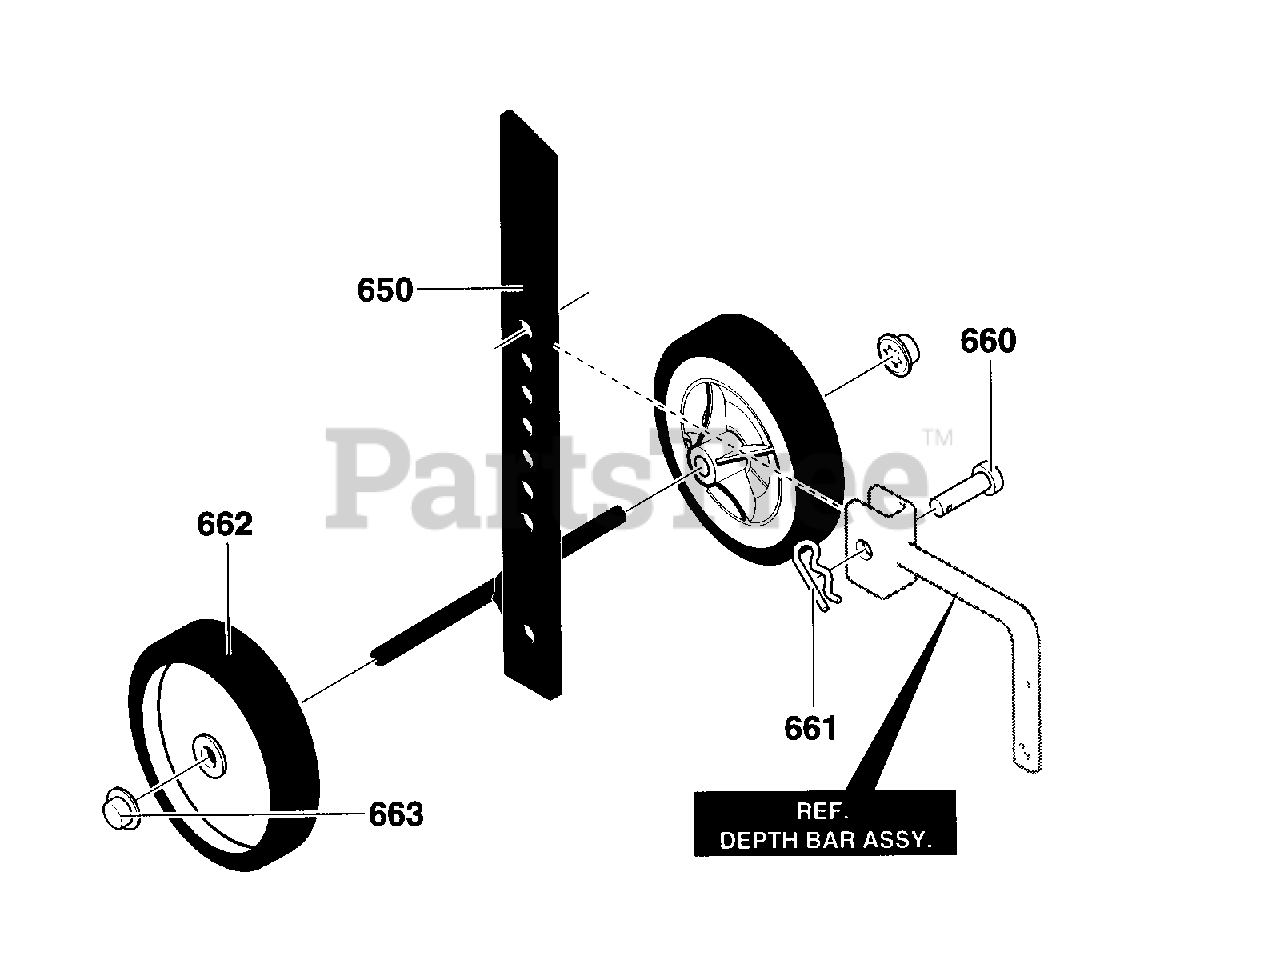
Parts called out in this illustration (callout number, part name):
650	WHEEL SUPT,ASSY
660	PIN, CLEVIS .321X.75BR
661	PIN, HAIR 53DIAX1.62LG
662	TIRE & RIM,SEPU 5.0 X 1.(696)
663	NUT, PUSH ON 3/8"
